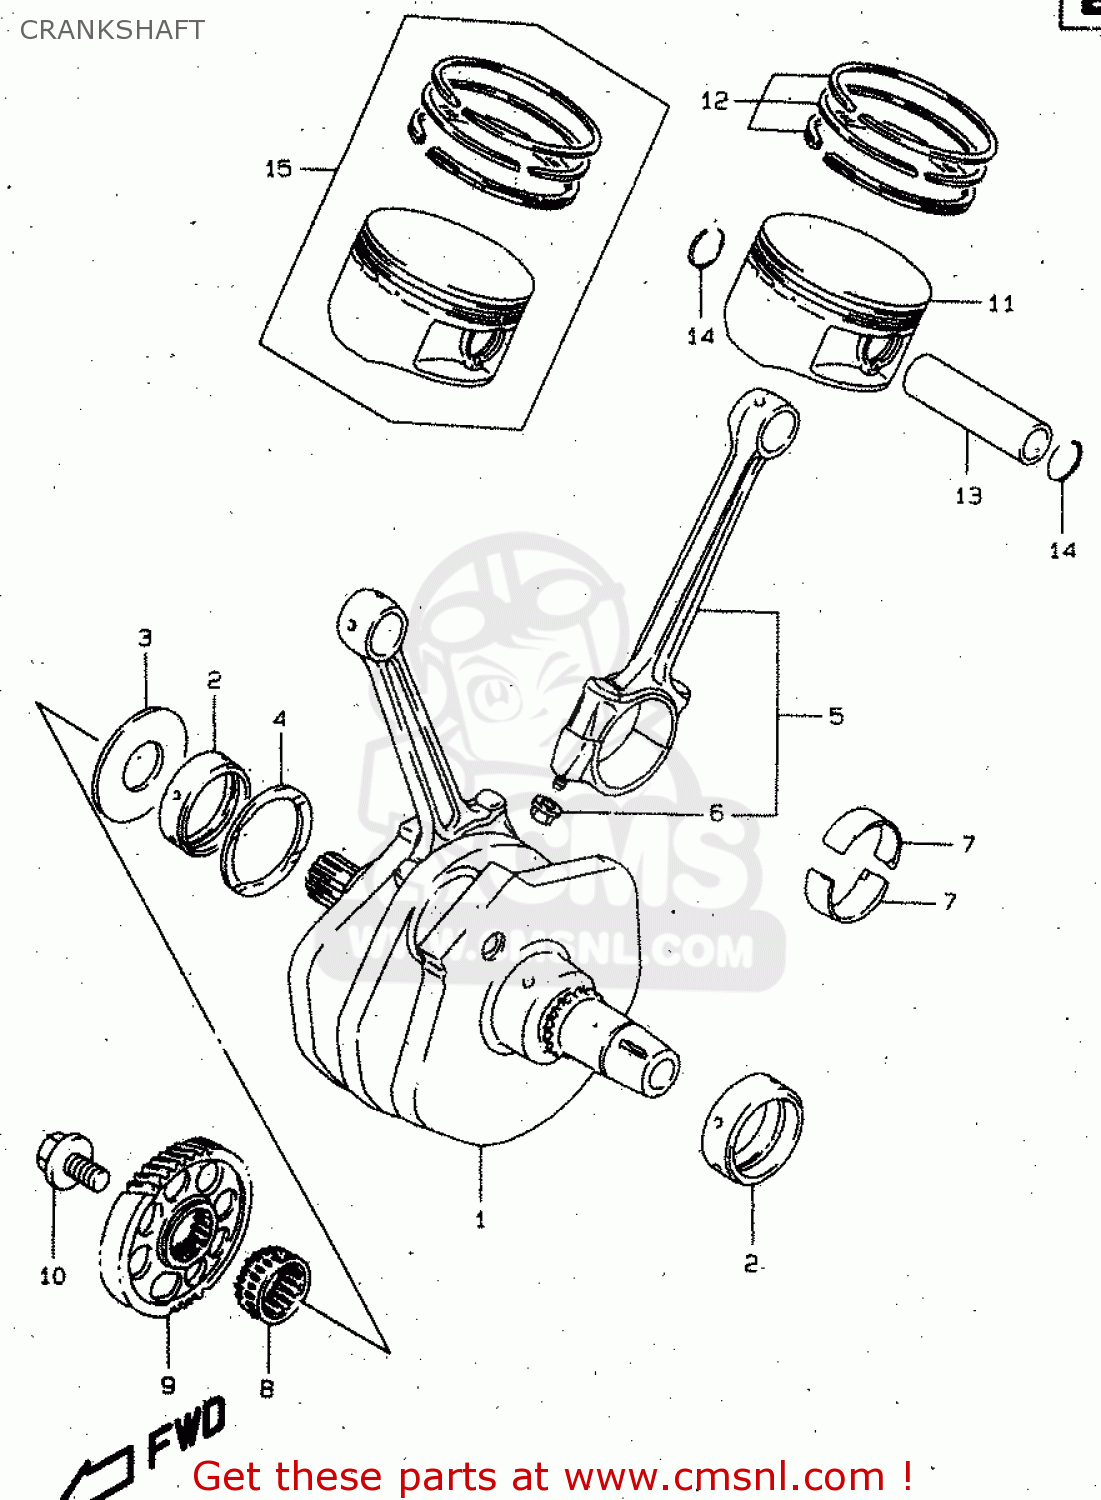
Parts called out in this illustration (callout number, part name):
1	CRANKSHAFT SET
2	METAL,CRANKSHAFT
3	WASHER,CRANK THRUST
4	PLATE,CRANK THRUST
5	CONNECTING ROD ASSY
6	NUT
7	METAL,CRANK PIN
8	SPROCKET,CAM CHAIN DRIVE,R
9	GEAR,PRIMARY DRIVE
10	BOLT(14X28)
11	PISTON (94.00MM)
12	RING SET,PISTON
13	PIN,PISTON
14	CIRCLIP
15	PISTON SET(OS:0.5)
